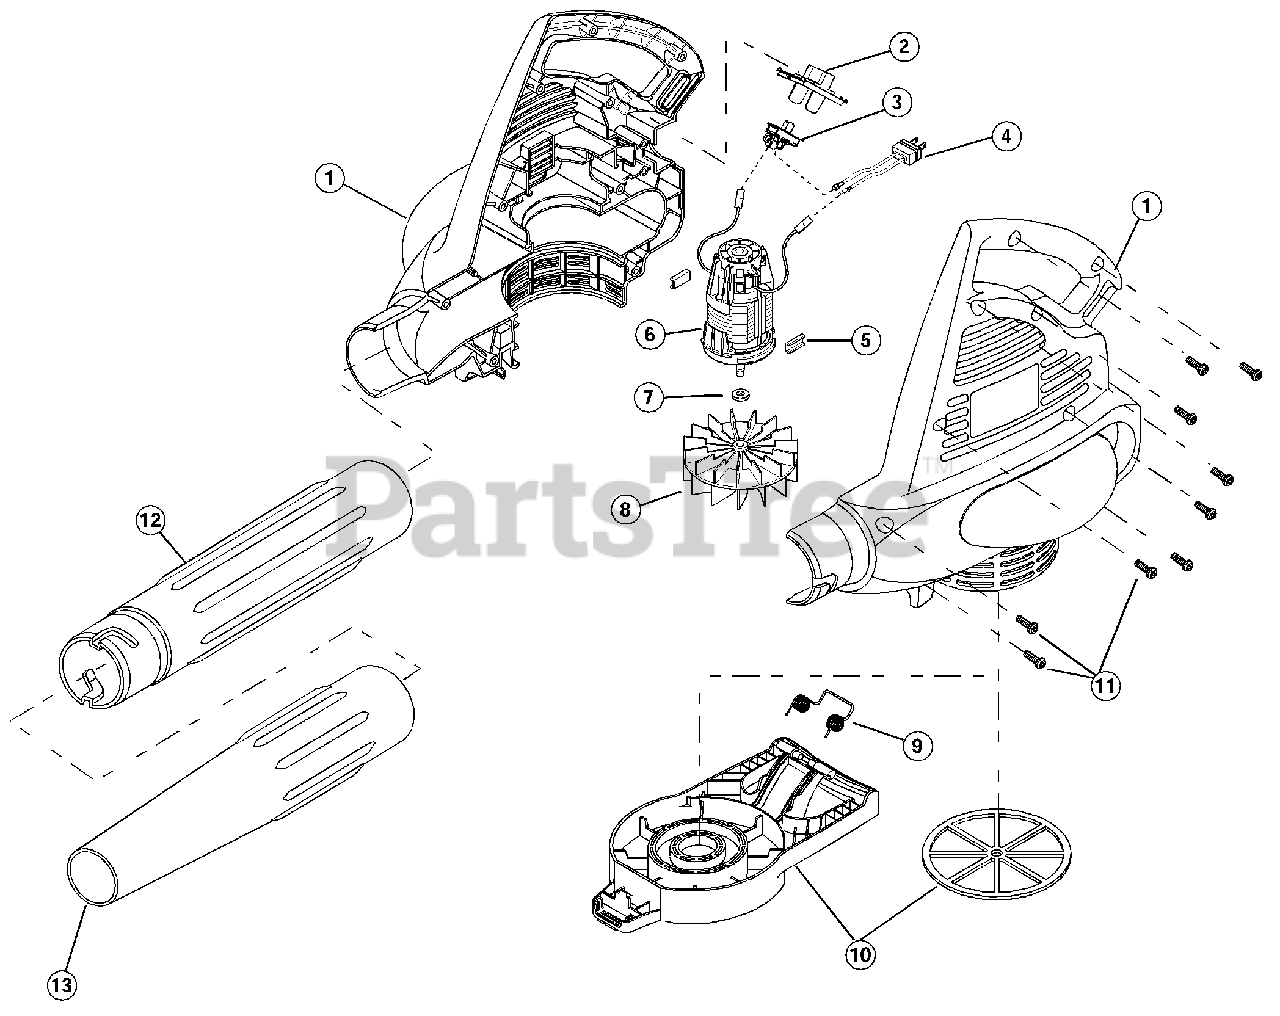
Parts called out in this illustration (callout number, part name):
1	Housing Set
2	Switch Cover
4	Power Cord
5	Motor Pad
6	Motor
8	Impeller
10	Inlet Cover w/Handle
11	Screw (11 Pack)
12	Blower Tube
